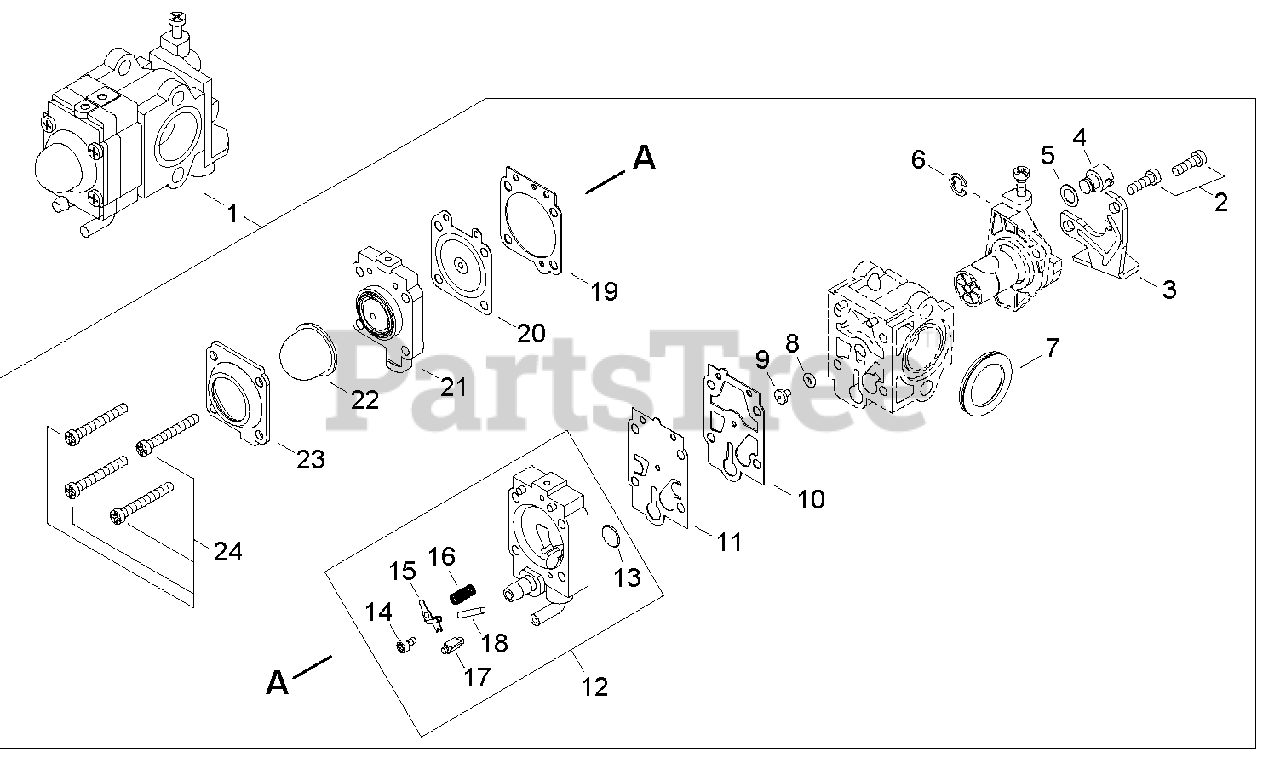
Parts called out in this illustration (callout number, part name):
1	CARBURETOR - WYJ-488
3	BRACKET, THROTTLE CABLE
7	RING, PACKING
9	JET, MAIN #37
10	GASKET, PUMP
11	DIAPHRAGM, FUEL PUMP
12	BODY ASSY, PUMP
13	SCREEN, FUEL INLET
15	LEVER, METERING
16	SPRING, METERING LEVER
17	VALVE, INLET NEEDLE
18	PIN, METERING LEVER
19	GASKET, METERING DIAPHRAGM
20	DIAPHRAGM, METERING
21	BODY ASSY, PURGE
22	BULB, PURGE
23	RETAINER, PURGE BULB
